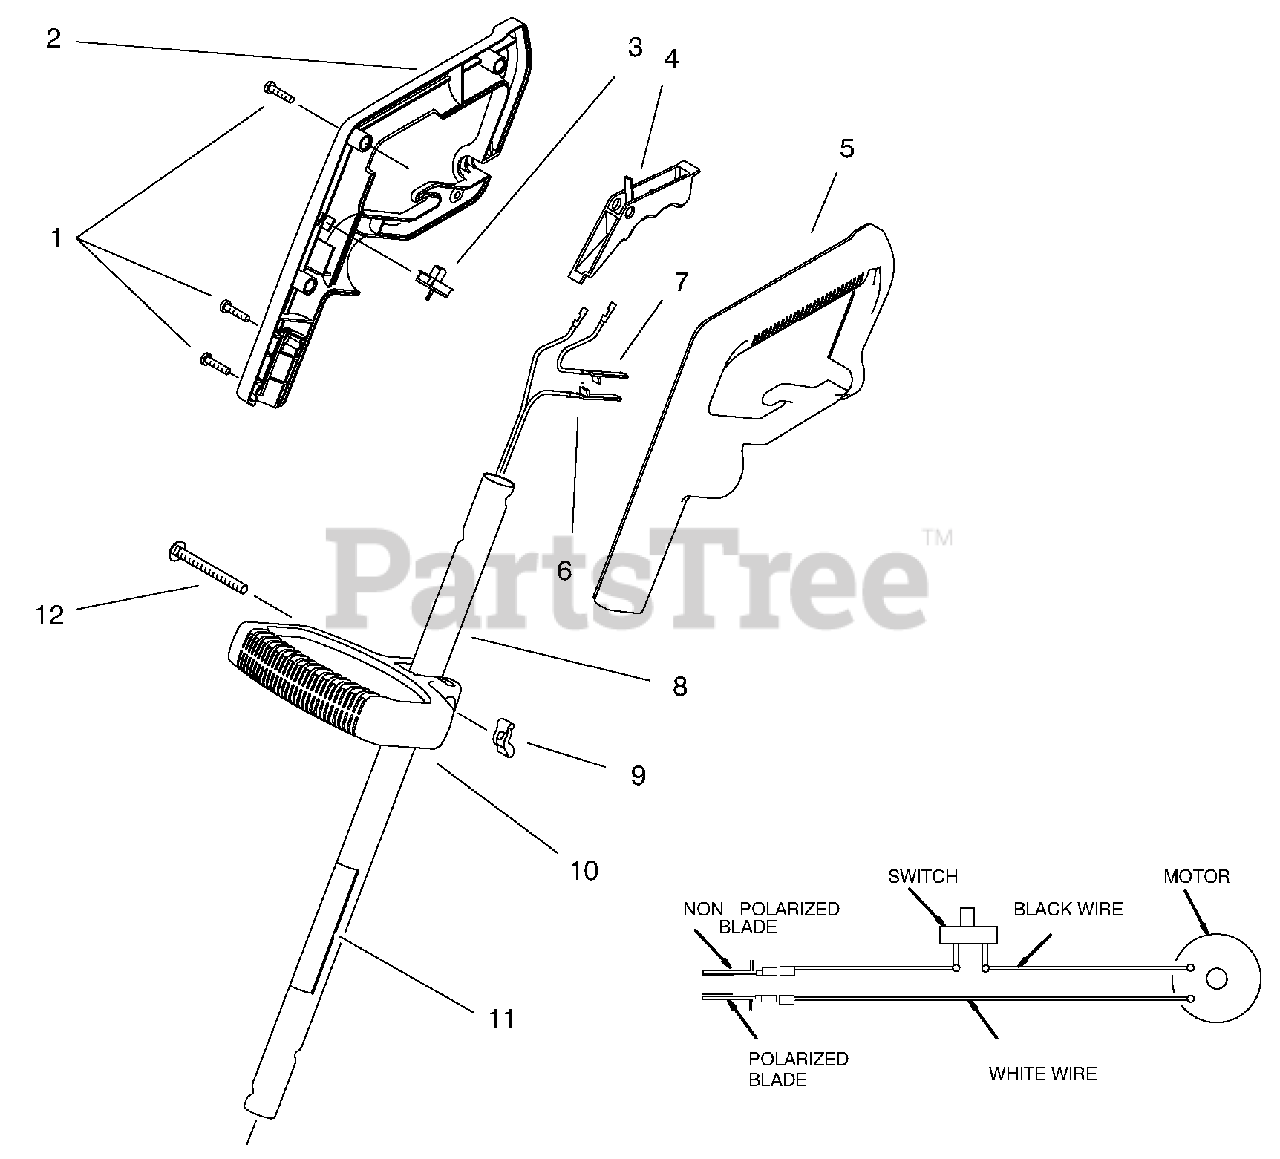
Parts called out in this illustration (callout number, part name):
1	SCREW-PPH
2	GRIP-HAND,RH
5	GRIP-HAND,LH
6	HARNESS-WIRE
7	WIRE-ASSEMBLY,JUMPER
8	Tube Assembly (Incl. Ref. #11)
9	1/4"-20 STAMP WNG NUT
10	MID HANDLE
11	DECAL-WARNING
12	SCREW-CARR.25-20 X 2.50
